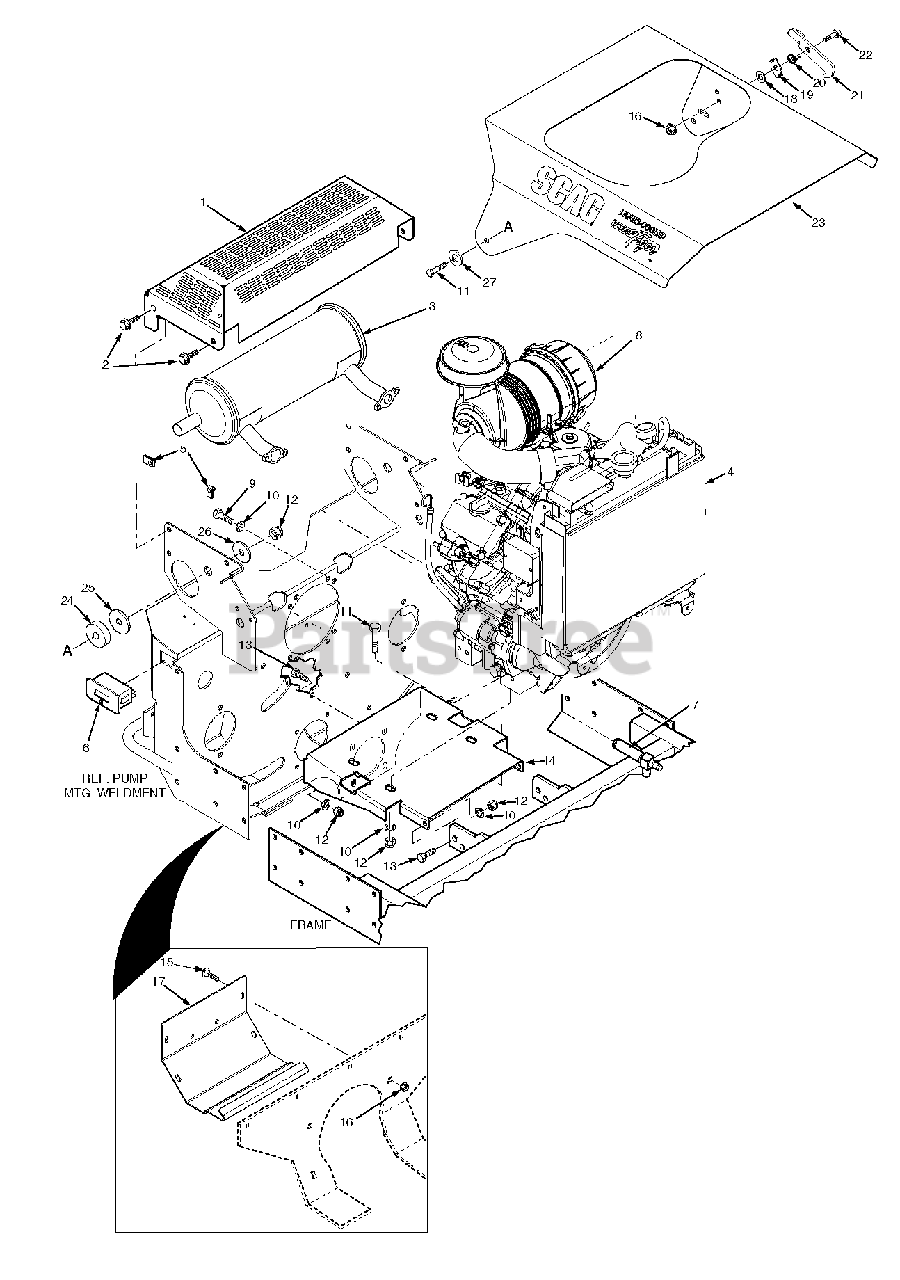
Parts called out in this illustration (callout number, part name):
1	Muffler Guard (Kawasaki
1	Muffler Guard (Briggs & Stratton)
2	Screw, Hex Serrated Flange 1/4-20 x 3/4"
3	Muffler (Kawasaki)
3	Muffler (Briggs & Stratton)
4	Screen Weldment, Radiator (Kawasaki Only)
5	U-Nut, 1/4-20
6	Hour Meter
7	Oil Drain, 2.6" (Kawasaki Only)
7	Oil Drain, (BV Only)
8	Engine, Kawasaki 750KA (Available only through Kawasaki)
8	Engine, Kawasaki 791DFI (Available only through Kawasaki)
8	Engine, Briggs & Stratton V-Twin Air-Cooled (Avail. only through B & S)
9	Bolt, M10-1.50 x 25mm
10	Lockwasher, 3/8" Spring
11	Bolt, Hex Head 3/8-16 x 1-3/4"
12	Nut, Hex Elastic Stop 3/8-16
13	Bolt, Hex Head 3/8-16 x 1-1/4"
14	Plate, Engine Mounting
15	Bolt, Carriage 5/16-18 x 3/4"
16	Nut, Hex Serrated Flange 5/16-18
17	Rear Cover
18	Flatwasher, 3/8 - .406 x .812 x .065
19	Lock, Hood Latch
20	Spring, Hood Latch
21	Latch, Hood
22	Bolt, Shoulder 5/16-18 x 1/2"
23	Hood Assembly w/Decals
24	Spacer, Hood
25	Disc, Anti-Friction
26	Flatwasher, 3/8 - .406 x 1.50 x 7 Gauge
27	Flatwasher, 3/8 - .391 x .938 x .105
